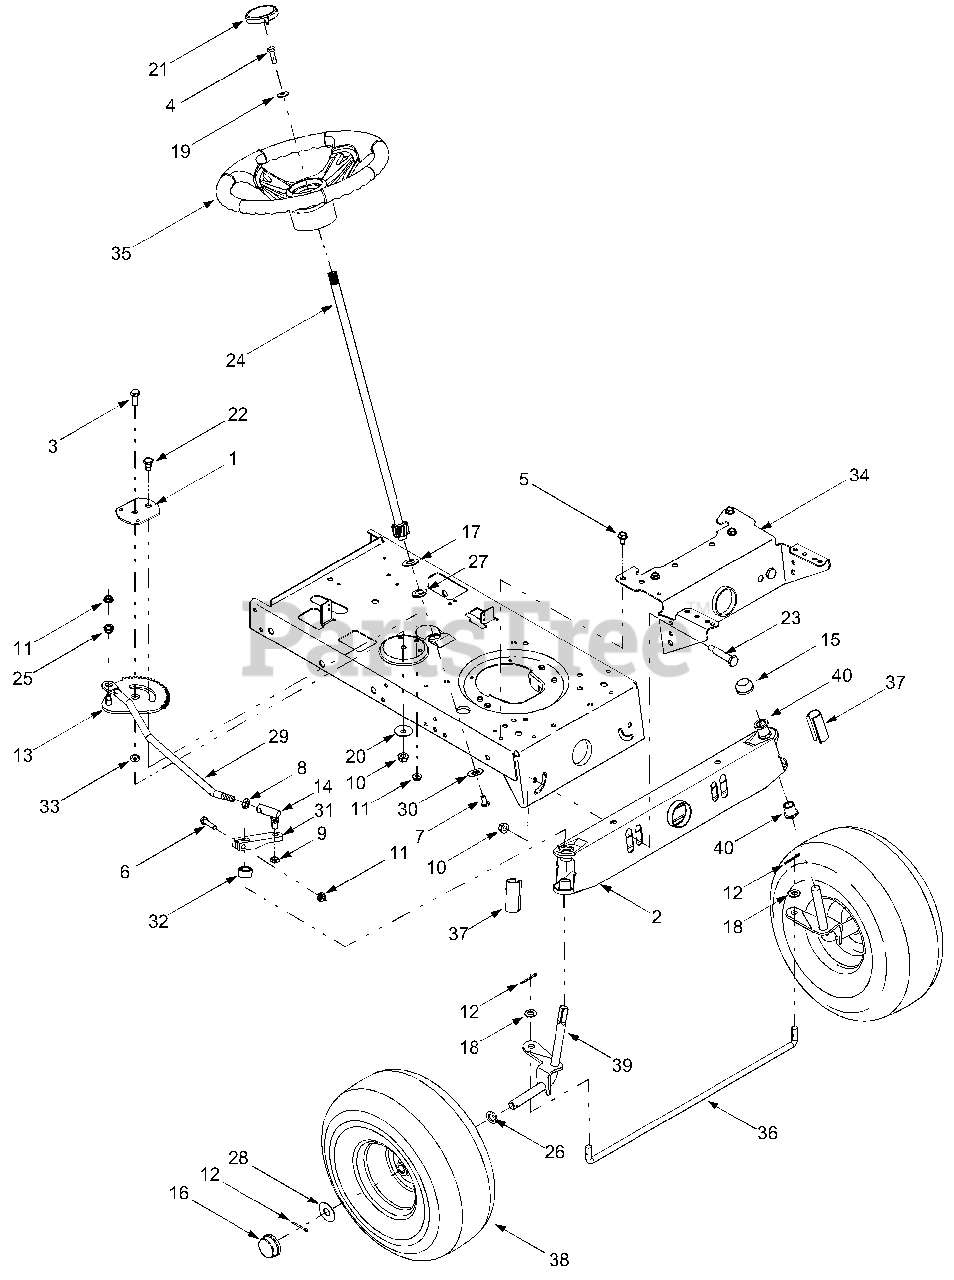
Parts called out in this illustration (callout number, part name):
1	Retainer Gear Segment Plate
4	Hex Cap Screw, 5/16-18 x 1.0
5	Self-tapping Screw, 5/16-12 x .75
6	Hex Cap Screw, 5/16-18 x 1.5
7	Machine Screw, 5/16-18 x .75
8	Jam Nut, 7/16-20 (Grade 2)
9	Jam Nut, 3/8-24
10	Flange Lock Nut, 3/8-16
11	Flange Lock Nut, 5/16-18
12	Cotter Pin, 1/8 x 1.25
13	Stearing Segment Gear
14	Ball Joint, 7/16 -20
15	Push Cap, .625
16	Hub Cap
17	Flat Washer, .64 x 1.24 x .060
18	Flat Washer, .474 x .879 x .064
19	Bell Washer, .34 x .872 x .060
20	Bell Washer, .391 x .380 x .062
21	Steering Wheel Cap, Small
21	Steering Wheel Cap, Small, w/ Spring
22	Shoulder Screw, .435 x .350, 5/16-18
23	Shoulder Screw, .498 x 2.045
24	Steering Shaft, 21.86
25	Plastic Bushing, .38 ID
26	Flat Washer, .64 x 1.0 x .12
27	Hex Flange Bearing, 5/8
28	Flat Washer, .635 x 1.589 x .06
29	Steering Drag Link, 7/16-20
30	Cap, 1.25 x .16
31	Steering Arm
32	Spacer, 1.0 x .645 x .56
33	Spacer, .380 x .625 x .21
36	Tie Rod, Non-adjustable
36	Tie Rod, Adjustable
37	Axle End Cap, Standard
38	Inner Bearing (Flange w/ Fitting)
38	Outer Bearing (Plastic Flange)
38	Air Valve
